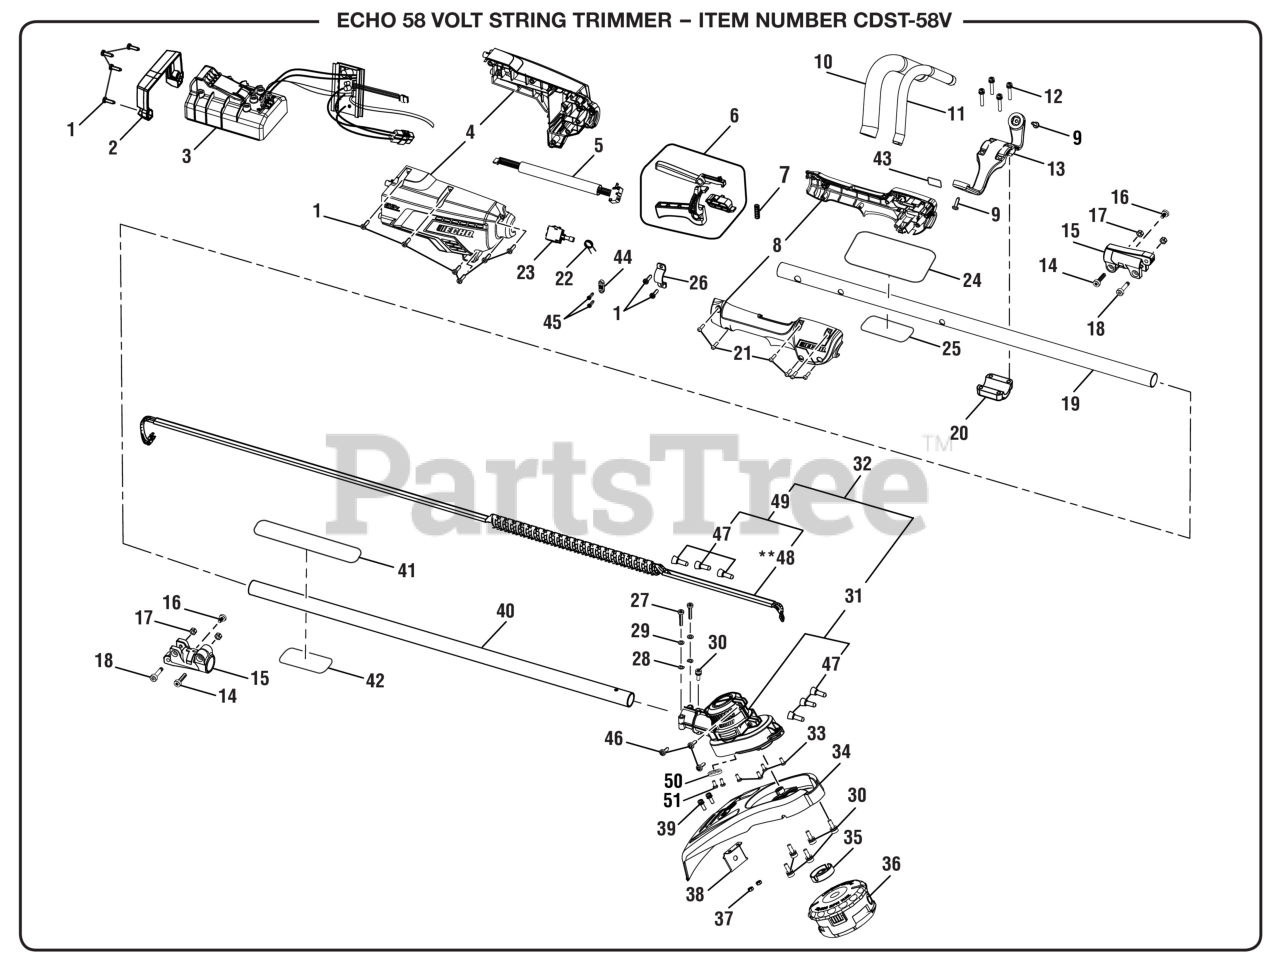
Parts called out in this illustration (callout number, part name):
1	Screw (M5 x 17.5 mm, T20 Torx Pan Hd.)
2	Battery Carriage Fastener
3	Battery Carriage & Motor Controller Assembly
4	Handle Housing Assembly
5	Switch and Wire Assembly
6	Switch Trigger, Lock-Out Button and ON/OFF Switch Assembly
7	Compression Spring (Trigger)
8	Rear Handle Housing Assembly
9	Screw (10-14 x 17 mm, T25 Torx Pan Hd.)
10	Foam Grip
11	Front Handle
12	Screw w/Washers (M5 x 26 mm, Pan Hd.)
13	Handle Bracket
14	Screw (M6 x 25 mm, T25 Torx Pan Hd.)
15	COUPLER
16	Screw (M5 x 10 mm, T25 Torx Pan Hd.)
17	Lock Nut (M6)
18	Screw (M6 x 26 mm, Recessed Hex Soc. Hd.)
19	Upper Boom Assembly
20	Clamp (Auxiliary Handle)
21	Screw (M4 x 14 mm, T20 Torx Pan Hd.)
22	Torsion Spring
23	Variable Signal Switch
24	Echo Logo Label (Upper Boom)
25	Data Label
27	Screw (M5 x 26 mm, T25 Torx Pan Hd.)
28	Washer (Special)
29	Washer (ID5.2 x OD10 x 0.8t)
30	Screw w/Washers (M5 x 12.5 mm, T25 Torx Pan Hd.)
31	Motor, Motor Housing and Gear Box Assembly
32	Motor, Motor Housing and Gear Box Assembly
33	Screw (M4 x 9 mm, T20 Torx Pan Hd.)
34	Grass Deflector
36	Stringhead Assembly
37	Hex Nut (M5)
38	Line Cutting Blade
39	Screw w/Washers (M5 x 12 mm, Pan Hd.)
40	Lower Boom Assembly
41	Warning Icon Label
42	Warning Label (French/Spanish)
43	Throttle Label
44	Cord Clamp
45	Screw (M4 x 13.5 mm, T15 Torx Pan Hd.)
46	Screw (M4 x 12 mm, T20 Torx Pan Hd.)
47	Wire Connector
48	Main Electric Wire
49	Main Electric Wire
50	Cord Clamp
51	Cap Screw (M4 x 11 mm, T20 Torx Hd.)
